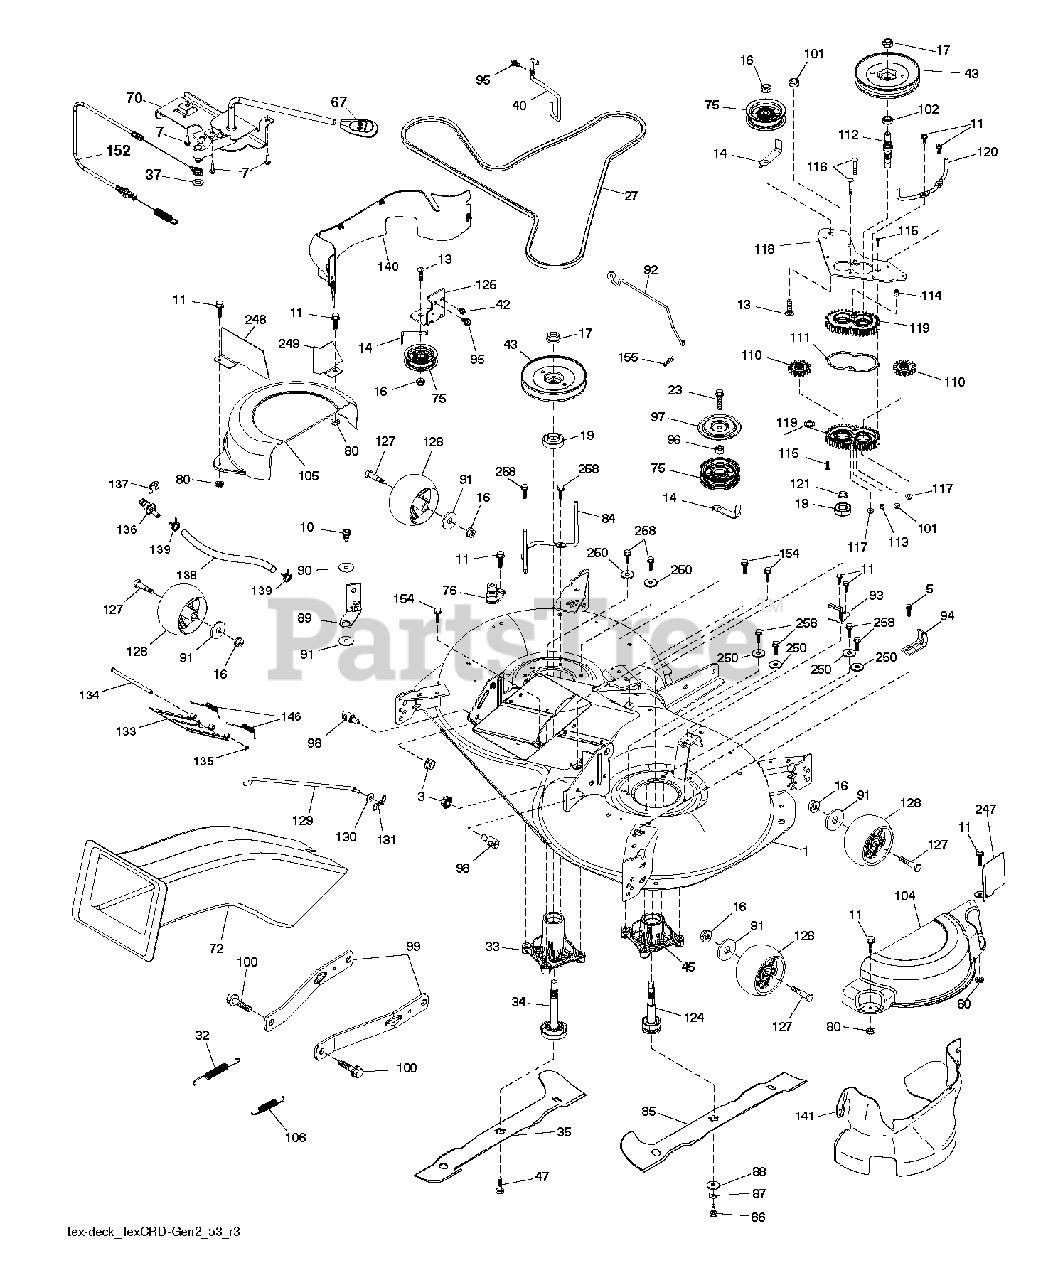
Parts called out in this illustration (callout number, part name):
3	NUT LOCK HEX FLANGE 5/16-18
5	BOLT.5/16HEX.WHS.HD
7	SCREW.#10 X 0.750.BOS THREAD
10	SCREW 3/8-16X1
11	SCREW.1/4-20X5/8
13	BOLT.3/8-16X1.50
14	KEEPER, BELT IDLER
16	NUT LOCK FLG 3/8-16 UNC
17	NUT.FLANGE.LOCK.TOP
23	SCREW LT
32	SPRING RETURN
40	KEEPER BELT ENGINE LH
42	SCREW
47	Screw, 7/16 X 20 X 1"
67	HANDLE.CLUTCH.CABLE.LT
70	CLUTCH.ASM.MANUAL.YT.PREDATORQ
72	CHUTE 10797 TEX GEN
75	FLAT IDLER PULLEY
80	PALNUT 1/4
87	LOCKWASHER
88	WASHER.BLADE
89	ARM BRAKE MOWER
90	SPACER.RETAINER
94	BRKT.CLUTCH.CABLE
95	SCREW, 3/8-16X3/4
98	STUD.FASTNER.W/ANTI-ROTATE
99	ARM.SUSPENSION.MOWER.R
100	BOLT.SHOULDER
102	SPACER BEARING
106	SPRING.BRAKE.RETURN.38"
110	CRD.GEAR.OUTPUT (3 2) (2 2)
114	VENT.BREATHER.1/8 NPT
117	NUT T
127	BOLT.SHOULDER.3/8-16X3-5/8
128	WHEEL. GUAGE RALLY
130	WASHER
131	PIN.COTTER.5/16.BOW TI
135	E-RING.5/16"
137	RING CLIP
140	GUARD.ASSEMBLY.107.LH.FRENCH
141	GUARD.ASSEMBLY.107.RH.FRENCH
155	RETAINER M
248	GUARD.STEEL.CRD.MANDR
249	GUARD.STEEL.CRD.MANDR
250	WASHER
258	Hex Washer Head Bolt, .313-18 X 1.19
